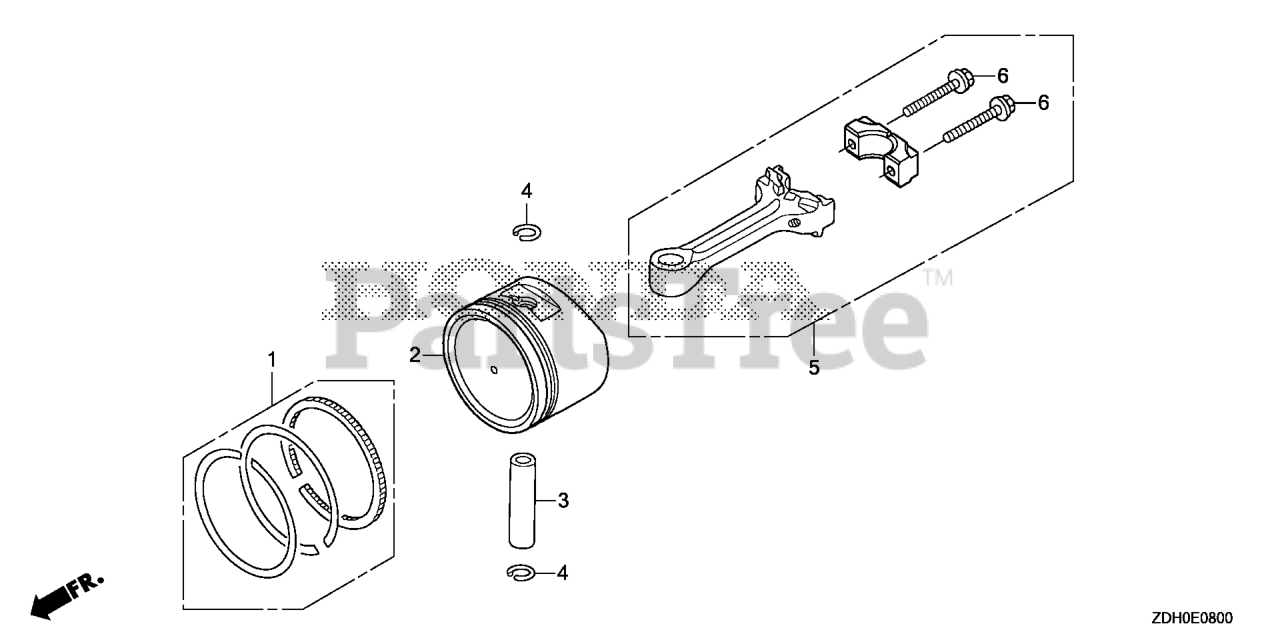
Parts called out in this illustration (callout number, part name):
1	RING SET, PISTON (STD)
2	PISTON (STD)
3	PIN, PISTON (10X33)
3	PIN, PISTON
4	CLIP, PISTON PIN (10MM)
5	ROD ASSY., CONNECTING
6	BOLT, CONNECTING ROD
